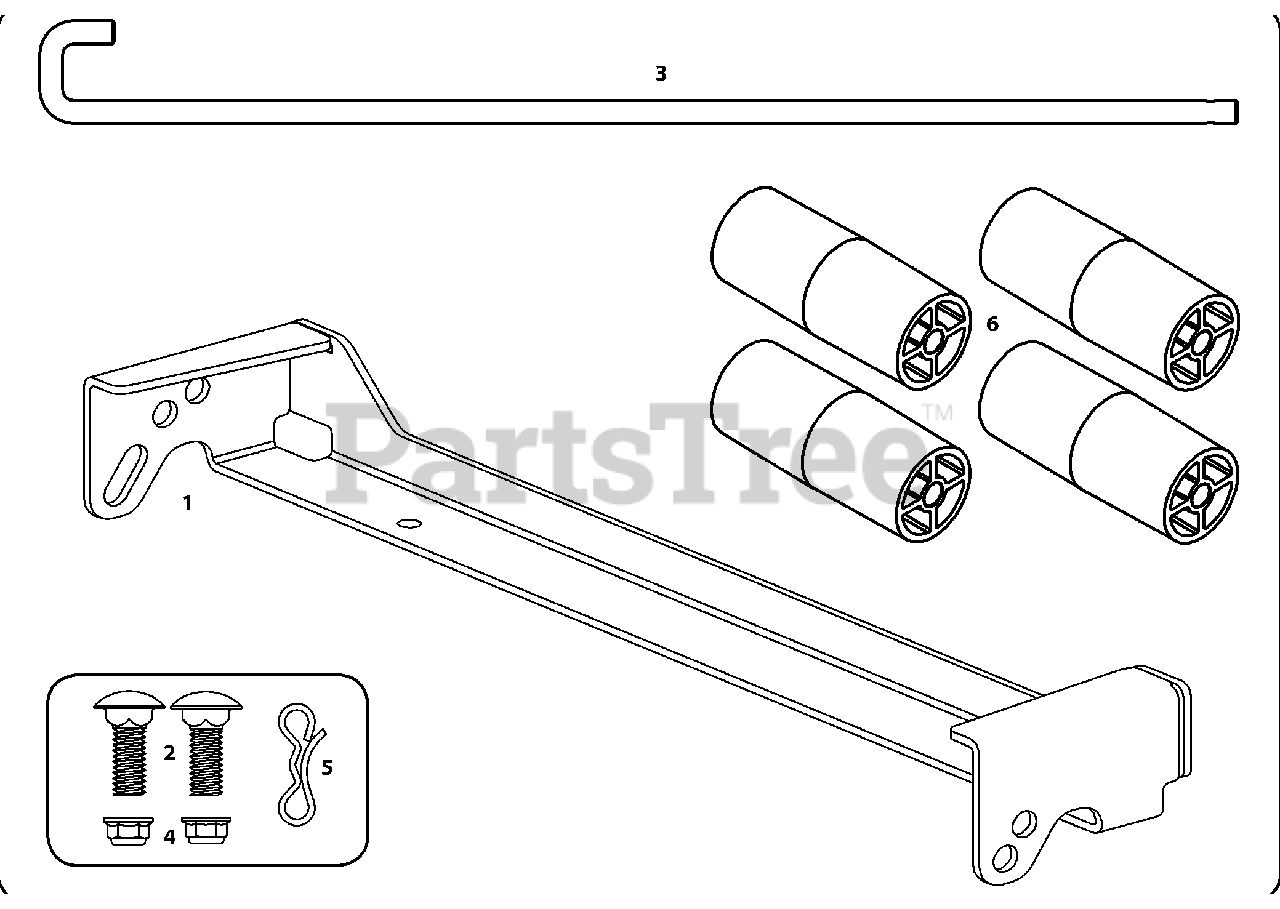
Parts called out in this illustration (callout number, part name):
1	Roller Bracket
2	Carriage Bolt, 3/8-16 x 1.00
3	Roller J-hook, 26"
4	Flange Lock Nut, 3/8-16
5	Bow-tie Cotter Pin, 91
6	Front Roller
